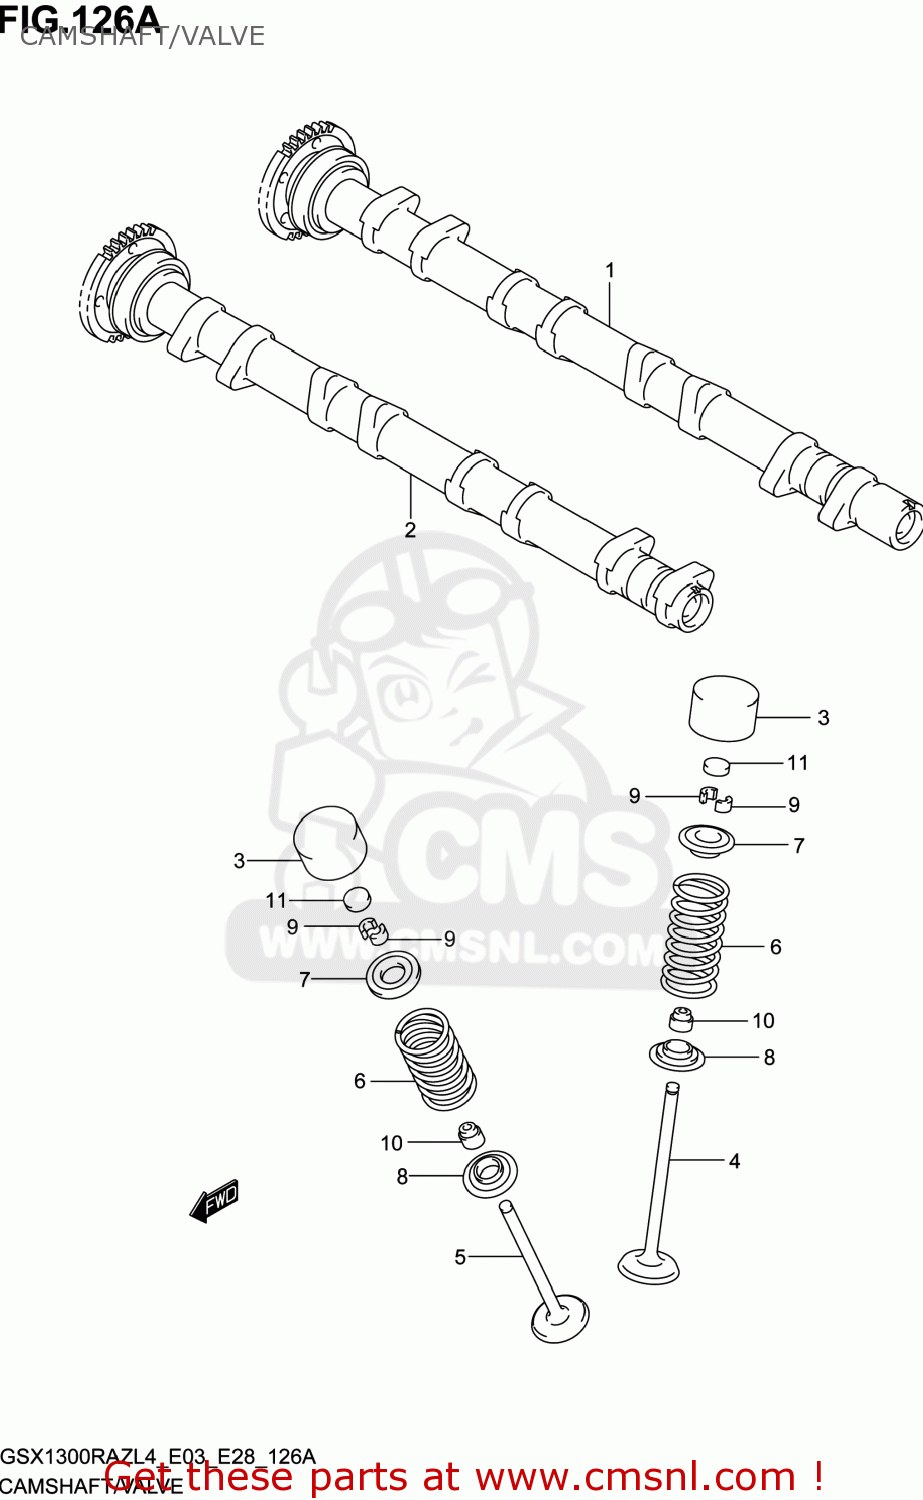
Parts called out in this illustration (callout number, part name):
1	CAMSHAFT,INTAKE
2	CAMSHAFT,EXHAUST
3	TAPPET
4	VALVE,INTAKE
5	VALVE,EXHAUST
6	SPRING,VALVE
7	RETAINER,VALVE SPRING
8	SEAT,VALVE SPRING
9	COTTER VALVE
10	SEAL,OIL(5X10X9.7)
11	SHIM,TAPPET(T:2.3)
12	SHIM SET,TAPPET
13	CASE,TAPPET SHIM
